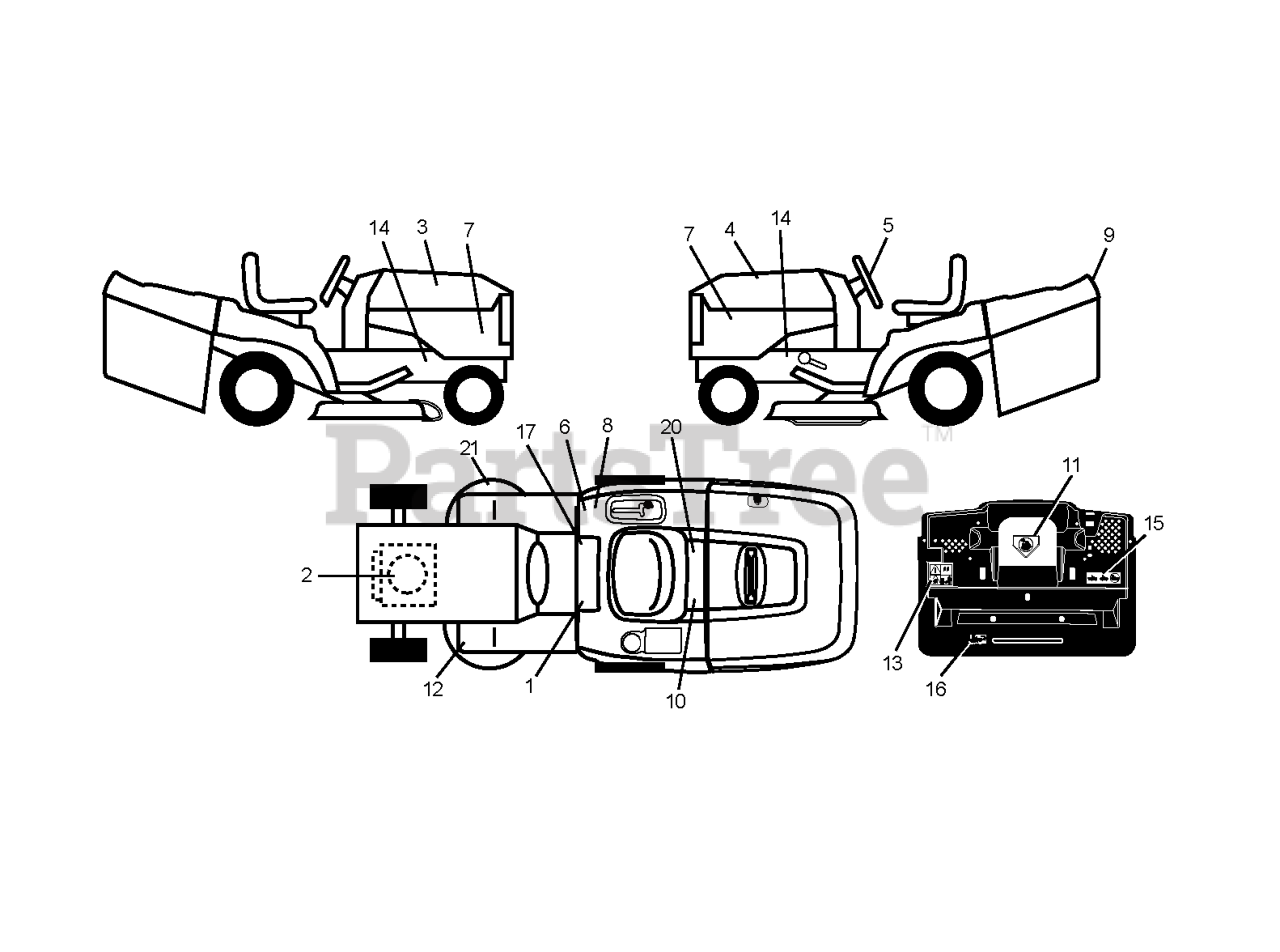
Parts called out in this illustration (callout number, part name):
1	DECAL READ OWNER'S MAN SYMS
5	DECAL.WHEEL.STEERING.HUSQ.PERM
6	DECAL CERTIFICATION
7	DECAL PNL SIDE
8	DECAL EUROPE STANDARD CE
9	DECAL FENDER HUSQ
10	DECAL BTRY SYMBOLS
11	DECAL MOWER CUT/FINGER
12	DECAL
13	Decal Warn Back Plate CRD
16	DECAL
17	DECAL PARK BRAKE
20	DECAL.BYPASS.FENDER.CRD.LT.YT
